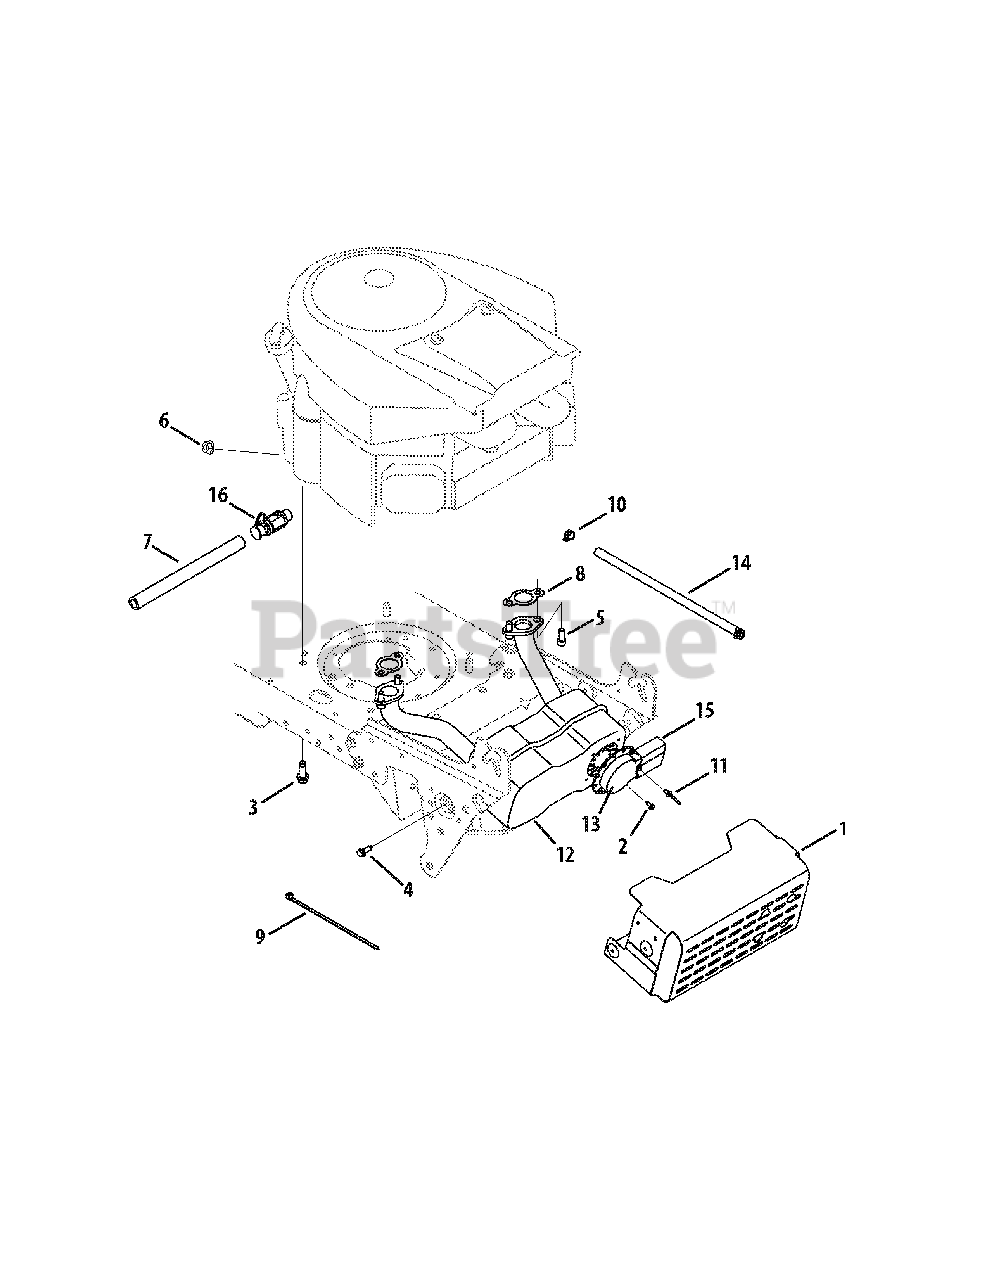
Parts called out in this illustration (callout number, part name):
1	Muffler Assembly Shield
2	AB Screw #8-18 x 0.5
3	TT Screw 3/8-16 x 1.00
4	TT Screw 1/4-20 x 0.750
5	Screw, 5/16-18 x .750
6	Sems Nut, 1/4-20
7	OIl Drain Extension Hose
8	Exhaust Gasket
9	Cable Tie
10	Hose Clamp
11	Pop Rivets, .188 x .300
12	Twin Inlet Muffler
13	Muffler Deflector
14	Fuel Line Hose
15	Long Muffler Deflector
16	Oil Drain Valve
